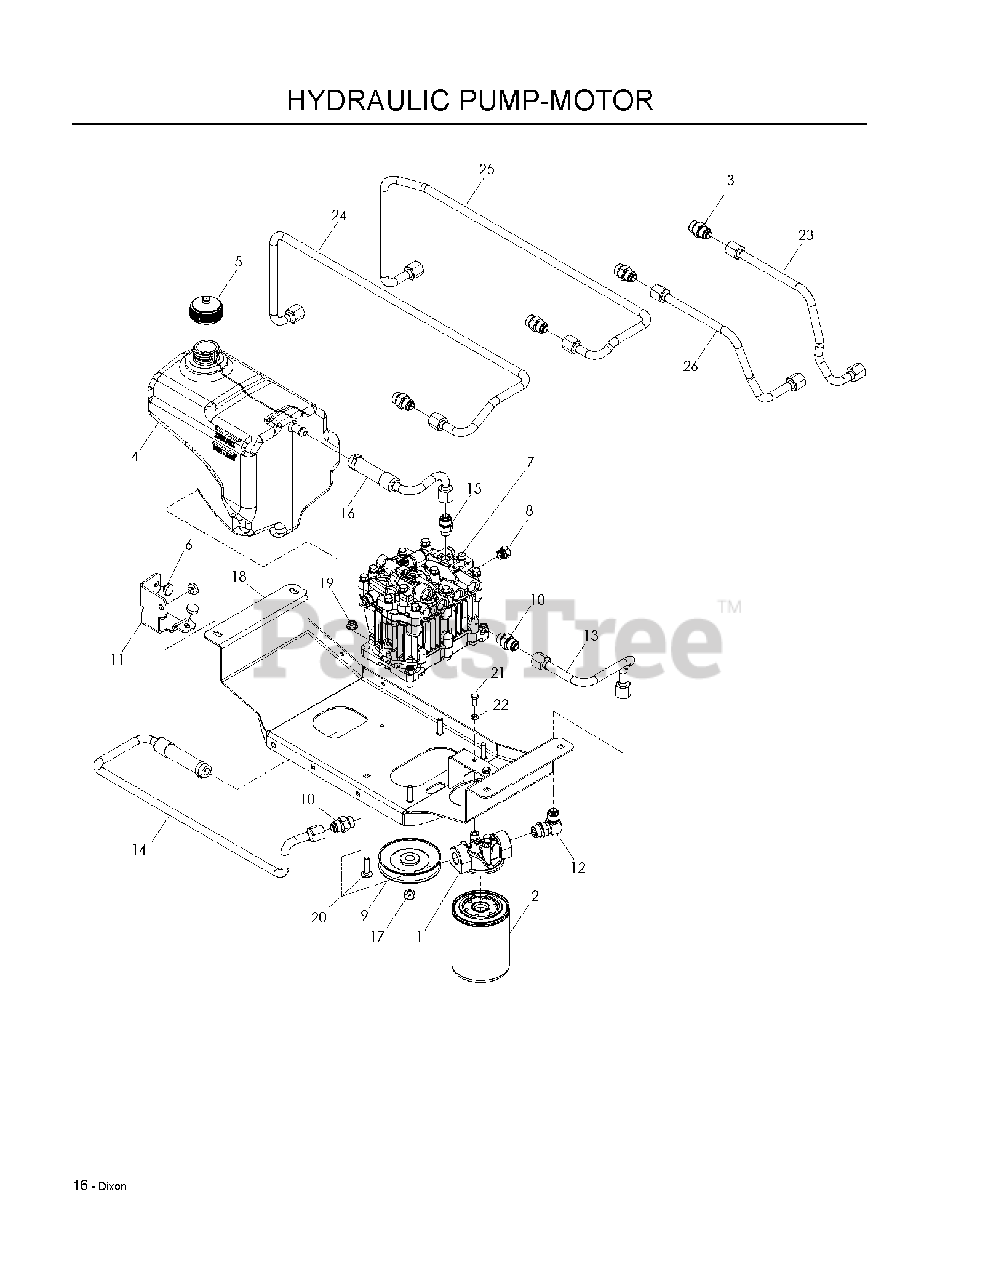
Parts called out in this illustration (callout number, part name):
1	FILTER HEAD
2	HYDRAULIC OIL FILTER
3	FITTING, STRAIGHT F6400-8-8-0
4	RESERVOIR HYDRO
5	HYDRAULIC CAP
6	GROMMET, BUMPER
7	PUMP, DUP10S (77808041201)
8	PLUG, 6408-6
9	PULLEY, PUMP
10	FITTING, 10-8 STRAIGHT
11	SUPPORT, RESERVOIR
12	FITTING, 10-8 90 DEG
13	HYD LINE, CHARGE
14	HYD LINE, INLET
15	FITTING, HYDRO
16	HYDRO LINE, CASE
17	NUT M10-1.5 L/H HEX
18	PLATE, PUMP
19	5/16-18 NYLOC FLANGE NUT
20	BOLT, CARRIAGE 5/16X1-1/4
21	HCS 1/4C X 5/8
22	LOCKWASHER 1/4"
23	HYDRO LINE, D
24	HYDRO LINE, A
25	HYDRO LINE, B
26	HYDRO LINE, C
